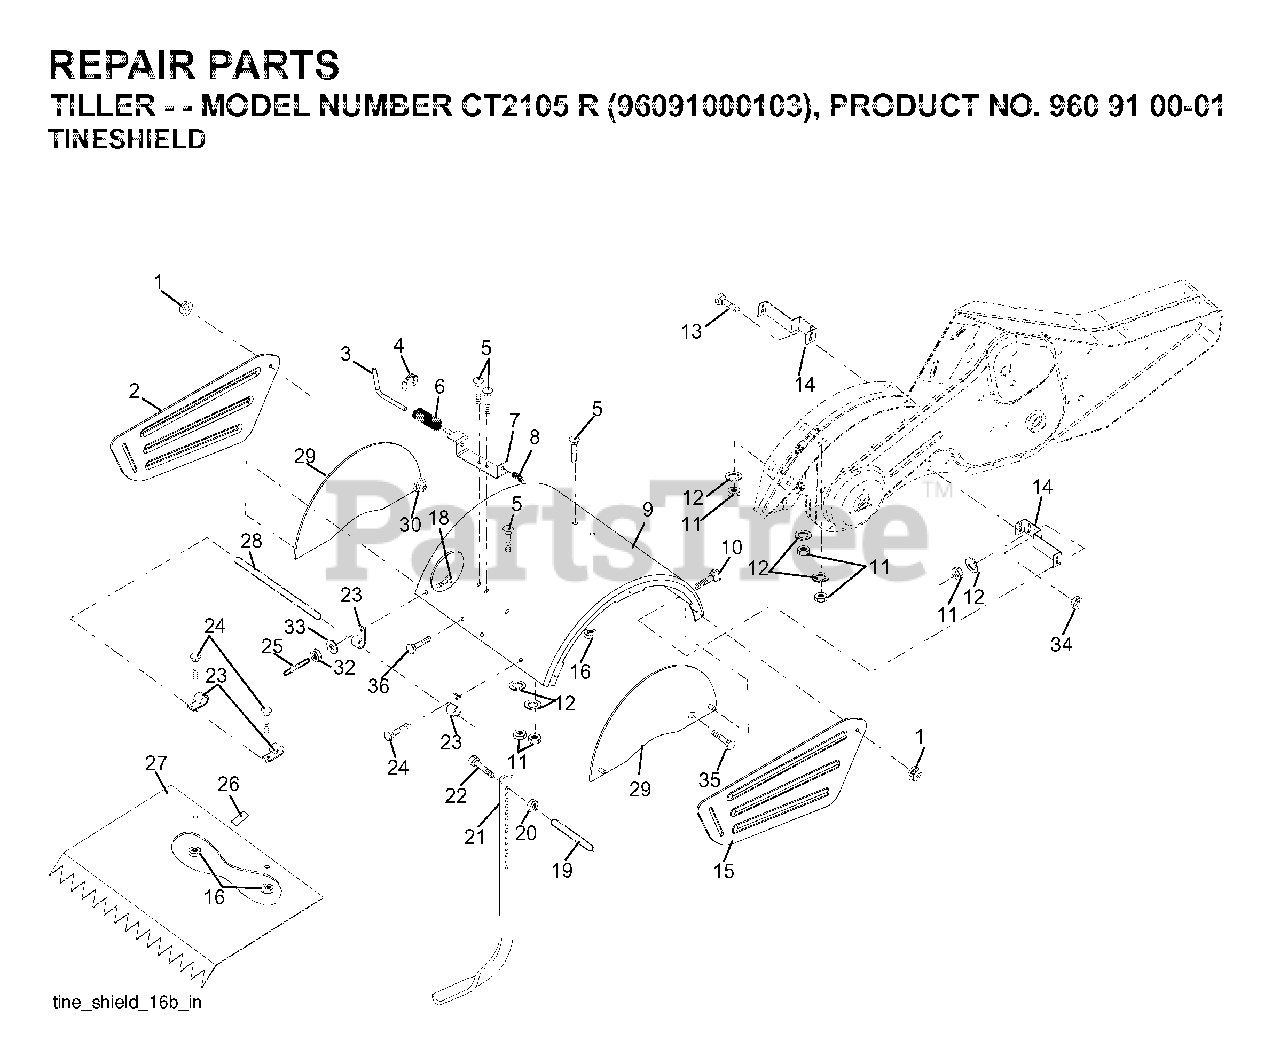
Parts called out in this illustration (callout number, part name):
1	NUT LOCK HEX FLANGE 5/16-18
3	STAKE PIN TI
4	RING, KLIP
5	BOLT, RDHD SQNK 5/16-18 X 3/4
6	SPRING TI
7	LATCH BRACKET TI
8	SPRING CRT
10	BOLT
12	LOCKWASHER
13	BOLT.CARRIAGE.5/16-18
14	BRACKET.TINE.SHIELD.TILLER
16	NUT T
20	NUT.HEX.3/8-16UNC
21	STAKE DEPTH CRT
22	BOLT.375-16
23	HINGE CRT
25	VINYL CAP TI
26	PAD IDLER TI
28	PIN.HINGE.TILLER
30	LOCKNUT-FLANGE 5/16-18
32	NUT
33	LOCKWASHER
34	NUT.71038.31-18.HEX.NYLOCK
35	BOLT
